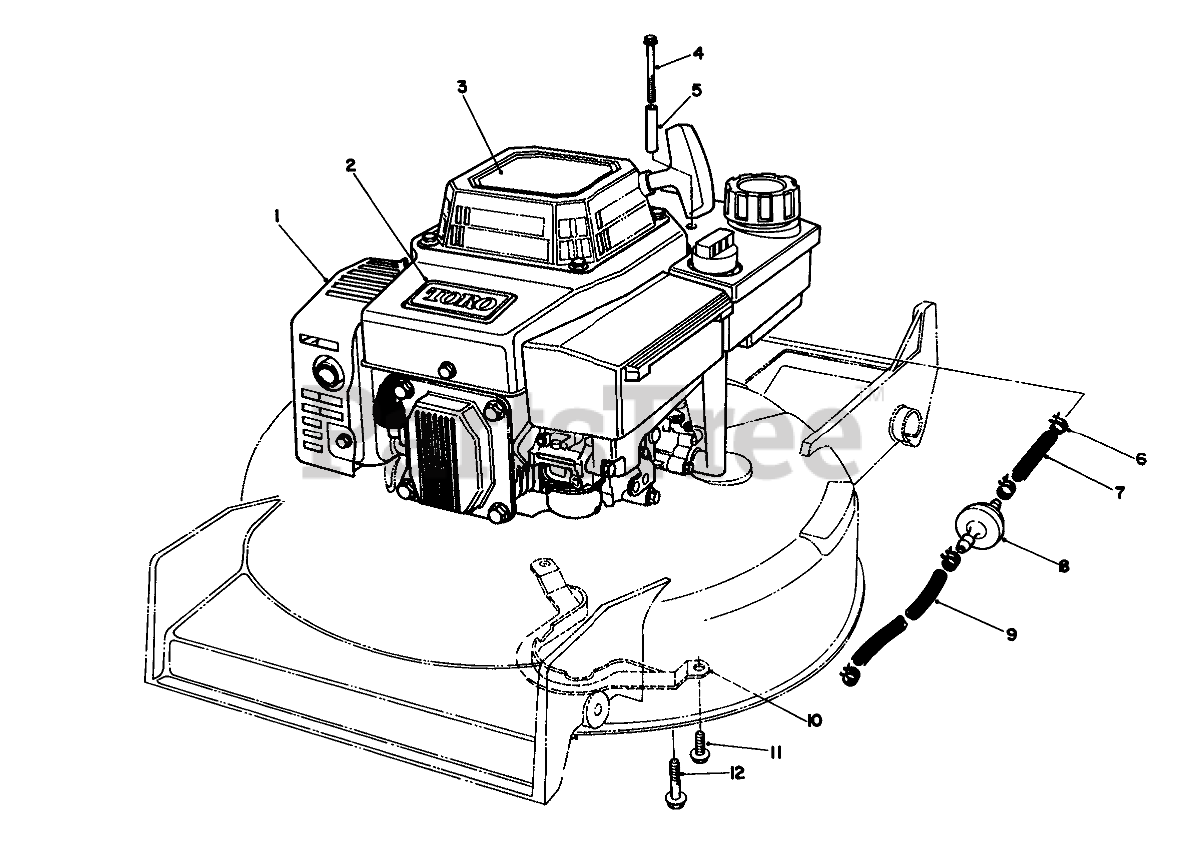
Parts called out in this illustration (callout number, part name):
1	ENGINE ASSY BBC OHV SU
2	TORO LOGO PLT
3	DECAL - OHV RECOIL
4	THRD FORMING SCREW
5	TUBULAR SPACER
6	CLAMP-FUEL LINE
7	LINE-GAS
8	FILTER-FUEL
9	HOSE-FUEL
10	BBC BELT GUIDE
11	SCREW-HWHTF
12	SCREW-HWHTF
